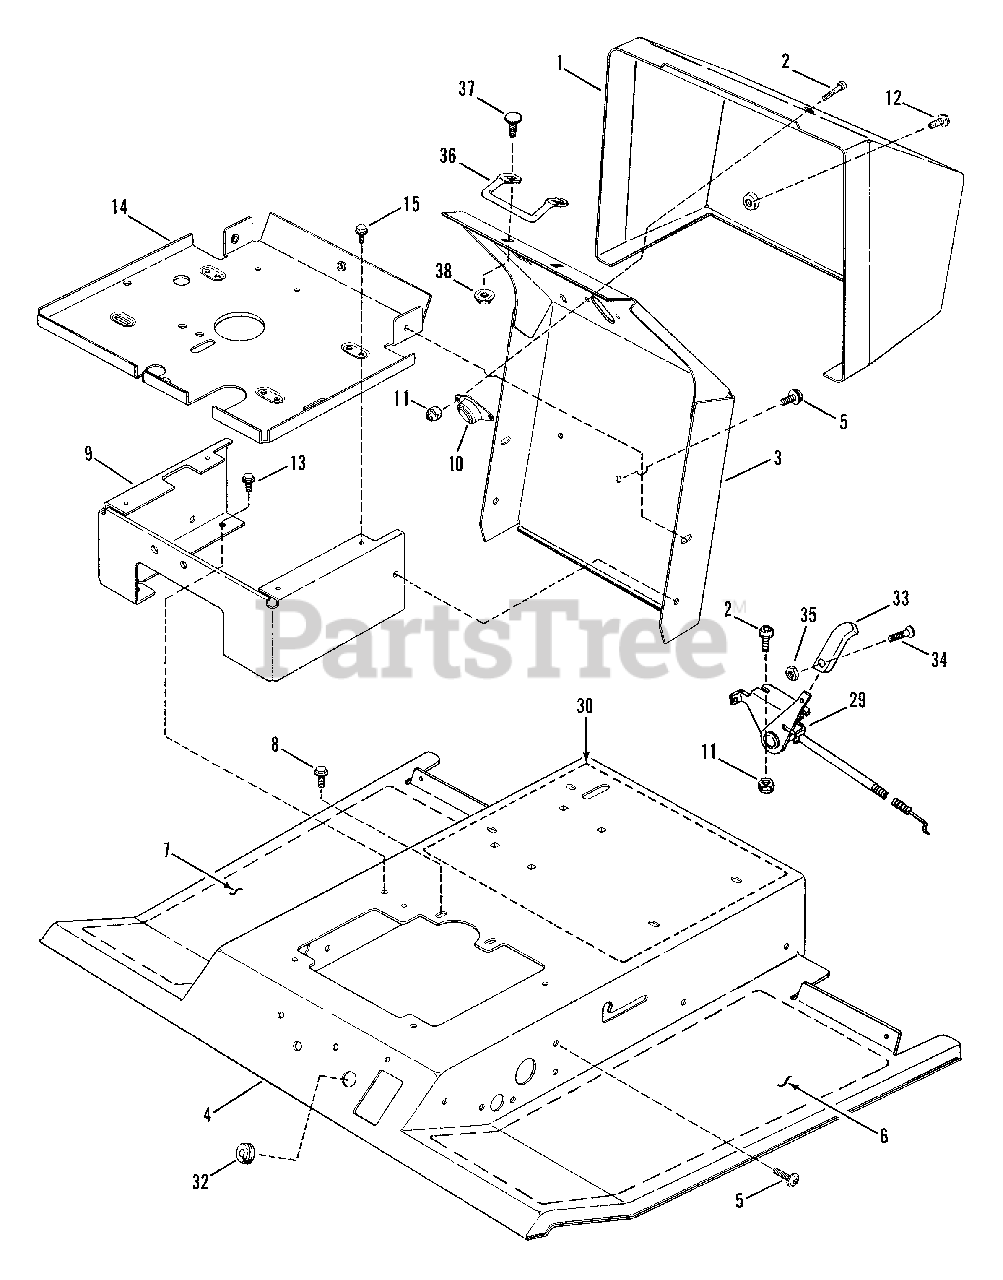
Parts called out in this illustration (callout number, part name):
1	PANEL, Dash
2	SCREW, 1/4-20 x 1" Phillips
3	SUPPORT, Steering Shaft
4	CHANNEL, Foot Rest
5	SCREW, 5/16-18 x 7/8" Torx, S.T.
6	TREAD, Left Side (Non-Skid)
7	TREAD, Right Side (Non-Skid)
8	SCREW, 5/16-18 x 5/8" Hex Cap S.T.
9	MOUNT, Fuel Tank/Battery
10	FLANGE ASSM'Y., Steering Shaft
11	NUT, 1/4-20 Hex
12	SCREW, #10-24 x 1/2" Self-Tapping
13	SCREW, 5/16-18 x 1/2" Self-Tapping
14	PLATE, Fuel Tank & Battery Mount
15	SCREW, 1/4-20 x 1/2" Hex Cap, S.T.
29	CONTROL, Throttle
30	DECAL, Caution & Instruction
32	GROMMET, 5/16 I.D. x 1" O.D. Split
33	HANDLE, Throttle Control
34	SCREW, #8-32 x 3/8" Recessed, Fillister Head
35	NUT, #8-32 Hex
36	ROD, Hood Latch
37	BOLT, 1/4-20 x 5/8" Flat Head Carriage
38	NUT, 1/4-20 Hex Flange Lock
